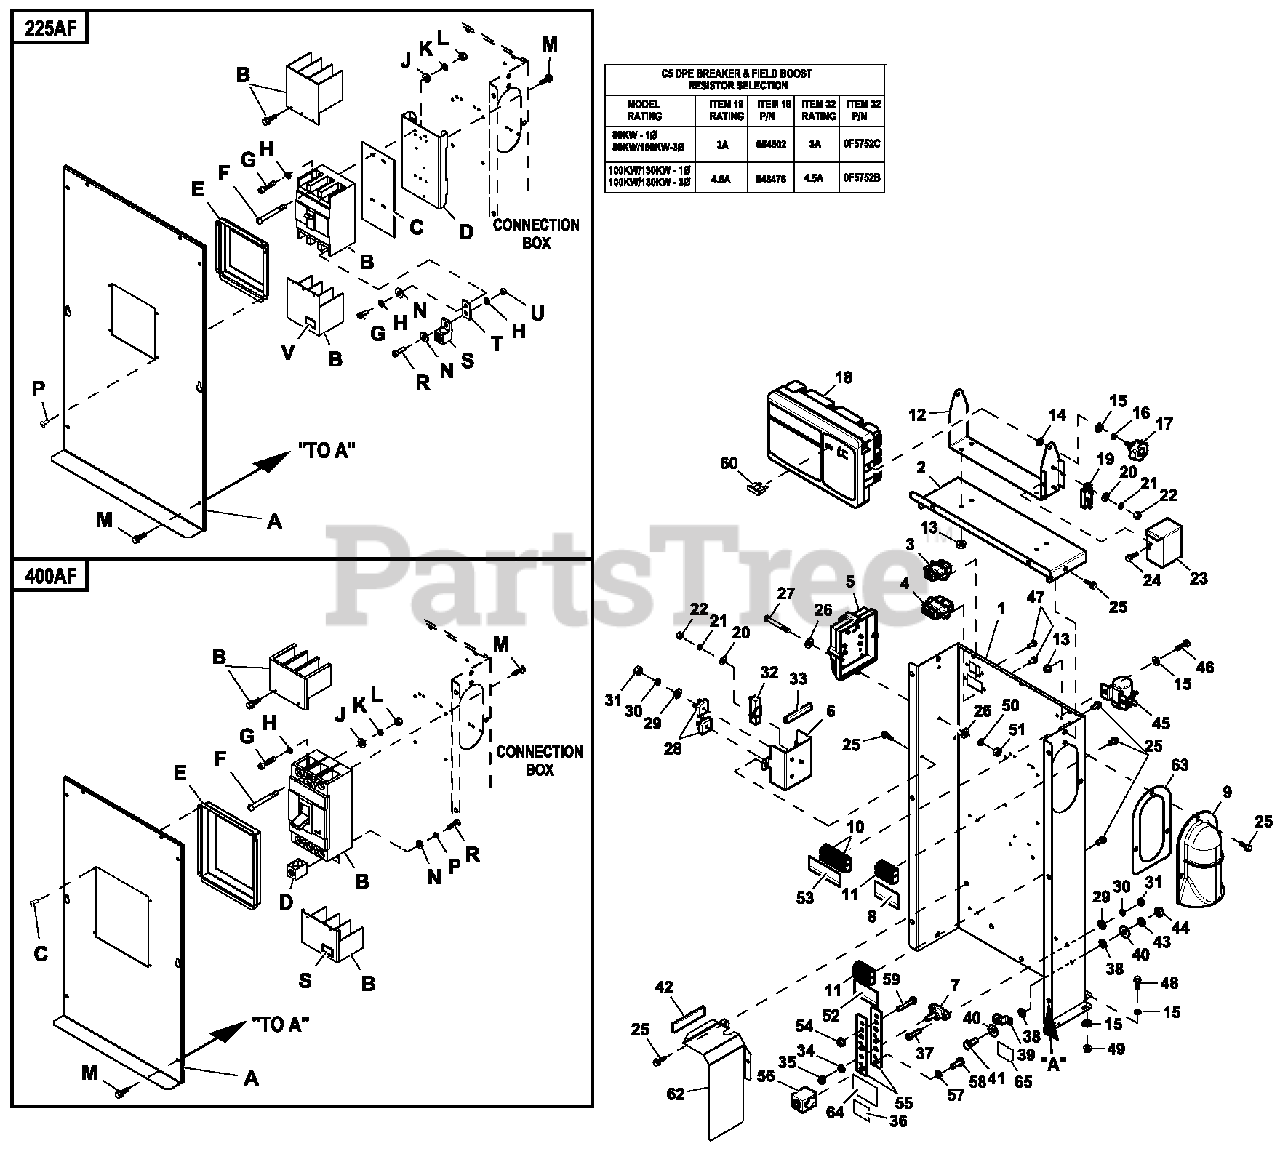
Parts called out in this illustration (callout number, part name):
1	BACK PANEL CONNBOX SUPPORT C5
2	TOP PANEL CONNBOX SUPPORT C2
3	MX150L SLRRMNT 22-18 8P W/O GA
4	MX150L SLRRMNT 22-18 12P W/OGA
5	ASSY PROG 2010 IGN MOD 10CYL
6	COVER VOLTAGE SHIELD
7	JUNCTION BLOCK 3/8-16
8	DECAL CUSTOMER POWER CONNECT
9	COVER WIRE ENTRY CONNBOX
10	TERM BLOCK 3P UL 12-20AWG
11	TERM BLOCK 4P UL 12-20AWG
12	BRACKET GIMBAL CONTROL PNL
13	NUT FLANGE M6-1.0 NYLOK
14	WASHER NYLON .257
15	WASHER FLAT 1/4-M6 ZINC
16	WASHER LOCK M6-1/4
17	KNOB M6-1.0 CONTROL PANEL
18	ASSY CTRL PROGRAMMED
19	SEE "C5 DPE BRKR & FIELD BOOST" CHART
20	WASHER FLAT M3
21	WASHER LOCK M3
22	NUT HEX M3-0.5 G8 CLEAR ZINC
23	COVER DPE BREAKER NEXUS RAW
24	SCREW HHTT M4-0.7 X 8 ZP
25	SCREW HWHT M6-1 X 16 N WA Z/JS
26	WASHER FLAT #10 ZINC
27	SCREW PPHM # 1 0 -3 2X 2
28	DIODE BRIDGE 1P 35A 1000V
29	WASHER FLAT M5
30	WASHER LOCK M5
31	NUT HEX M5-0.8 G8 CLEAR ZINC
32	SEE "C5 DPE BRKR & FIELD BOOST" CHART
33	TRIM VINYL BLACK 1/8GP (63"LG)
34	WASHER LOCK 3/8
35	NUT HEX 3/8-16 STEEL
36	DECAL CAUTION ELEC SHOCK SM
37	SCREW SHC M5-0.8 X 20 C12.9
38	WASHER LOCK EXT 7/16 STL
39	LUG SLDLSS 3/0-#4X 13/32 CU
40	WASHER FLAT 3/8-M10 ZINC
41	SCREW HHC M10-1.5 X 25 C8.8
42	TAPE ELEC 1/2 FOAM
43	WASHER LOCKM10
44	NUT HEX M10-1.5 G8 YEL CHR
45	RELAY SOLENOID 12VDC PNL MNT
46	SCREW HHC M6-1.0 X 20 C8.8
47	SCREW HHSP #10 X 3/8 HI-LOW
48	SCREW HHTT M6-1.0 X 16 ZYC
49	NUT TOP LOCK FL M6-1.0
50	WASHER LOCK #10
51	NUT HEX #10-32 STEEL
52	DECAL CUSTOMER CONTROL CONNECT
53	DECAL CONBOX TB1 CONNECTIONS
54	NUT HEX FL WHIZ M8-1.25
55	BUSBAR NEUTRAL BLOCK 390
56	LUG SLDLSS 600/250-1/0X1/4-28
57	WASHER LOCK 1/4-M6 SS
58	SCREW HHC 1/4-28 X 3/4 G5
59	SCREW HHC M8-1.25 X 45 C8.8
60	FUSE ATO TYPE 7.5AMP (BROWN)
62	SHIELD HIGH/LOW C5 RAW
63	GASKET WIRE ENTRY COVER
64	DECAL NEUTRAL
65	DECAL GROUND LUG
A	COVER CB G 225AF C5
B	CB 0150A 3P 480V G 225AF
C	INSUL CB 225AF
D	STANDOFF CB BOX CONBOX
E	COVER CB DISH 3P G 225AF
F	SCREW RHM #8-3 2X3 -1 /4
G	SCREW SHC M8-1.25 X 20 G8
H	WASHER LOCK M8-5/16
J	WASHER FLAT #8 ZINC
K	WASHER LOCK#8-M4
L	NUT HEX #8-32 STEEL
M	SCREW HWHT M6-1 X 16 N WA Z/JS
N	WASHER FLAT 5/16-M8 ZINC
P	RIVET POP .125 X .275 SS
R	SCREW SHC M8-1.25 X 25 C12.9
S	LUG SLDLSS 300 MCM-6 AL/CU
T	BUS BAR 200A LUG ADAPTOR
U	NUT HEX M8-1.25 G8 CLEAR ZINC
V	DECAL TERMINAL SHOCK HZD BI
A	COVER CB G 400AF C5
B	CB 0250A 3P 480V G 400AF
C	RIVET POP .125 X .275 SS
D	LUG SLDLSS 600/250-1/0X1/4-28
E	COVER CB DISH G 400AF C5
F	SCREW RHM 1 0 -3 2X 4
G	SCREW SHC M10-1.5 X 25 C12.9
H	WASHER LOCKM10
J	WASHER FLAT #10 ZINC
K	WASHER LOCK #10
L	NUT HEX #10-32 STEEL
N	WASHER FLAT 1/4-M6 ZINC
P	WASHER LOCK M6-1/4
R	SCREW HHC 1/4-28 X 1/2 G5
S	DECAL TERMINAL SHOCK HZD BI
